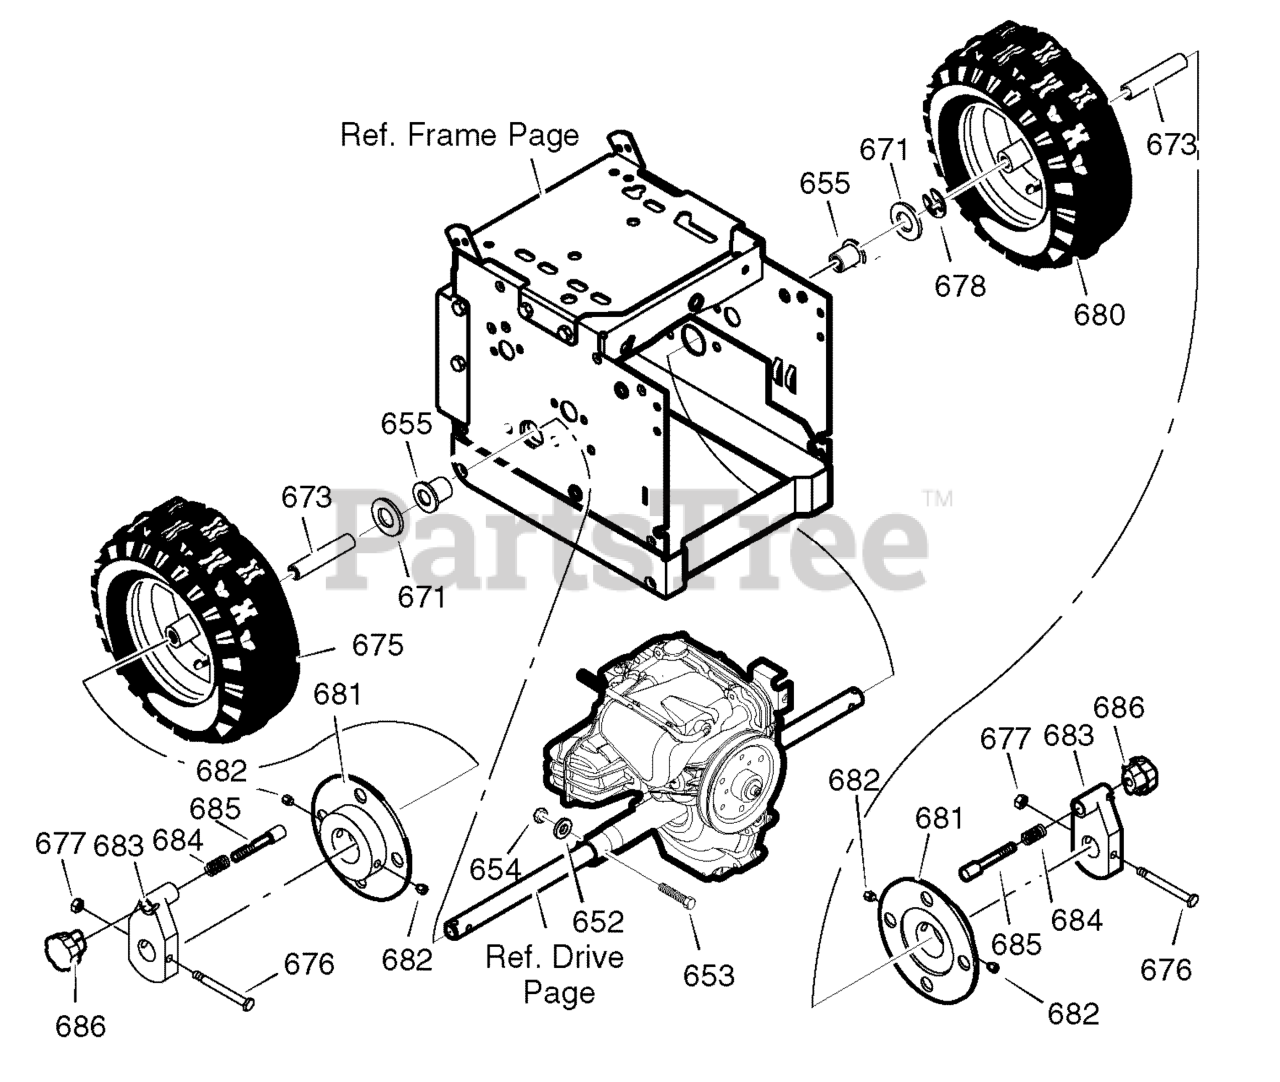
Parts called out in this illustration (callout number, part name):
653	SCREW, 1/4-20x1.75
654	NUT, 1/4-20
655	BEARING, AXLE
671	FLATWASHER
673	BUSHING, WHEEL
675	TIRE & RIM, RIGHT
676	SCREW, 1/4-20x2.25
677	NUT, 1/4-20
678	RING, RET
680	TIRE & RIM, LEFT
681	DISC, WHEEL
682	SCREW
683	HUB, WHEEL LOCK
684	Spring
685	YZ PIN, LOCK
686	KNOB *
